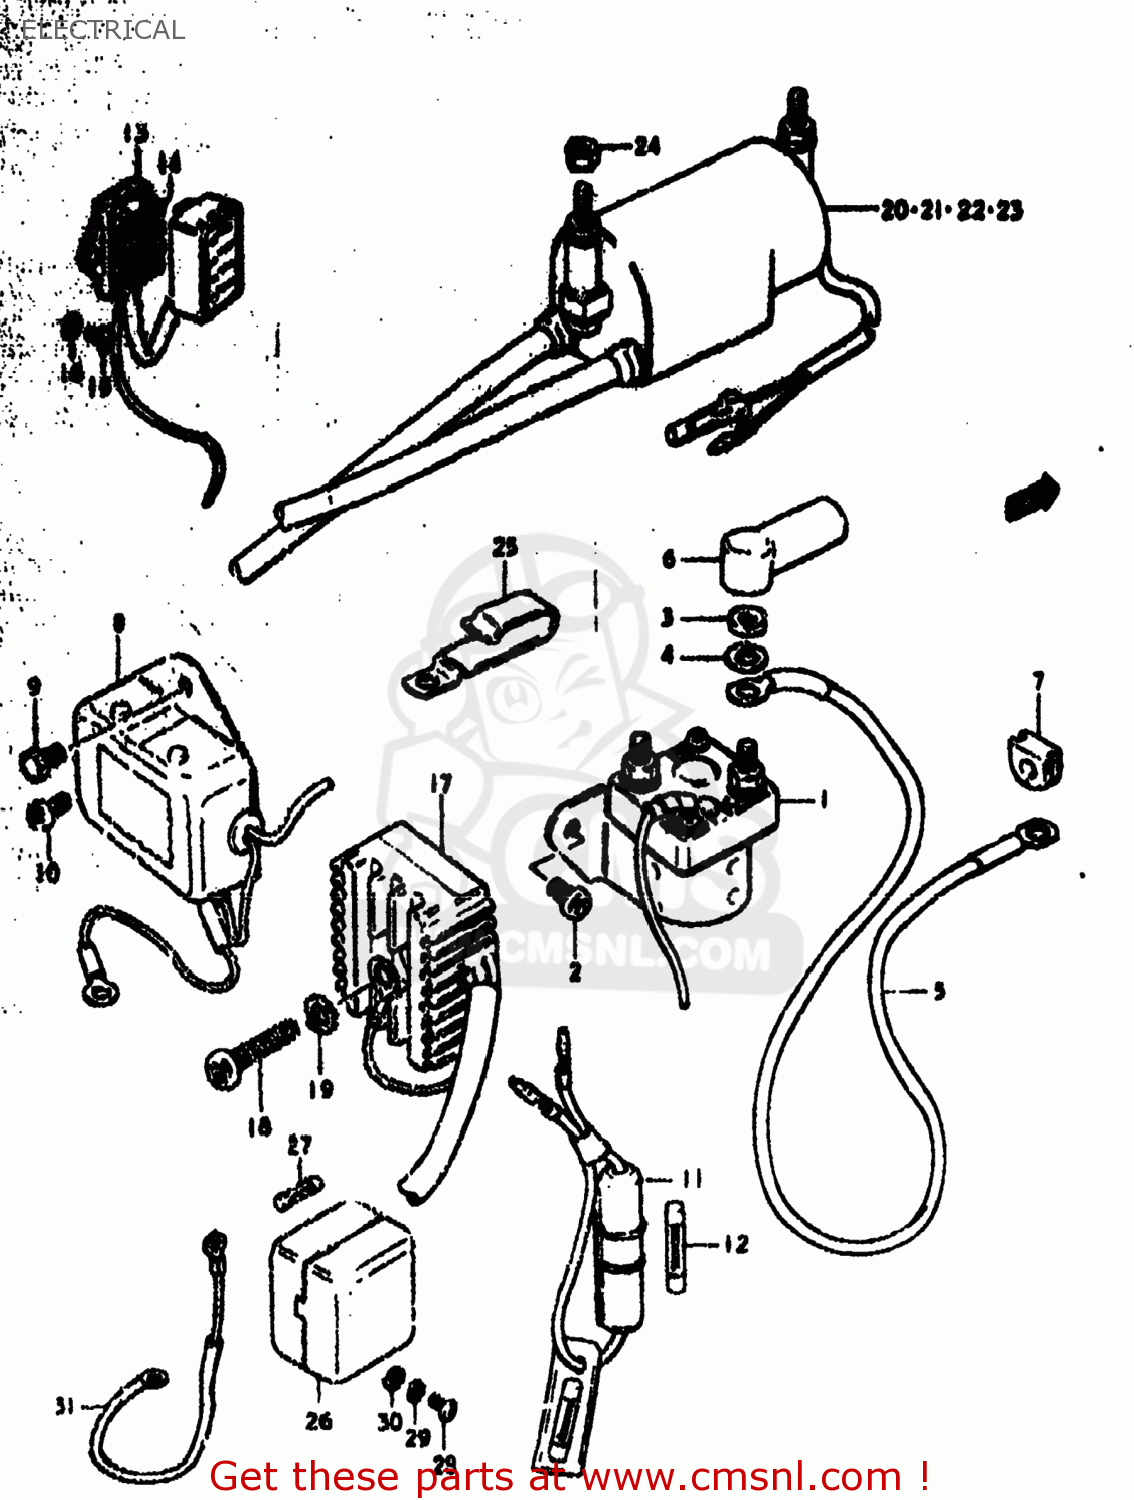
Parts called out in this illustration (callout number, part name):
1	RELAY ASSY,STARTING MOTOR
2	SCREW,6X6
3	NUT 6MM
4	LOCK WASHER
5	WIRE,STARTER MOTOR LEAD
6	CAP,STARTER RELAY
7	GROMMET,STARTER CABLE
8	REGULATOR ASSEMBLY
9	BOLT
10	SCREW
11	BOX ASSEMBLY,FUSE
12	FUSE(15A)
13	BOX ASSEMBLY,FUSE
14	FUSE(15A)
15	SCREW 6X12
16	WASHER
17	RECTIFIER ASSY
18	SCREW
19	LOCK WASHER
20	COIL ASSEMBLY,IGNITION
21	COIL ASSEMBLY,IGNITION
22	COIL ASSEMBLY,IGNITION
23	COIL ASSEMBLY,IGNITION
24	NUT
25	CLAMP
26	TERMINAL ASSEMBLY,POWER SO
27	FUSE(10A)
28	SCREW
29	LOCK WASHER
30	WASHER
31	WIRE,POWER SOURCE LEAD
